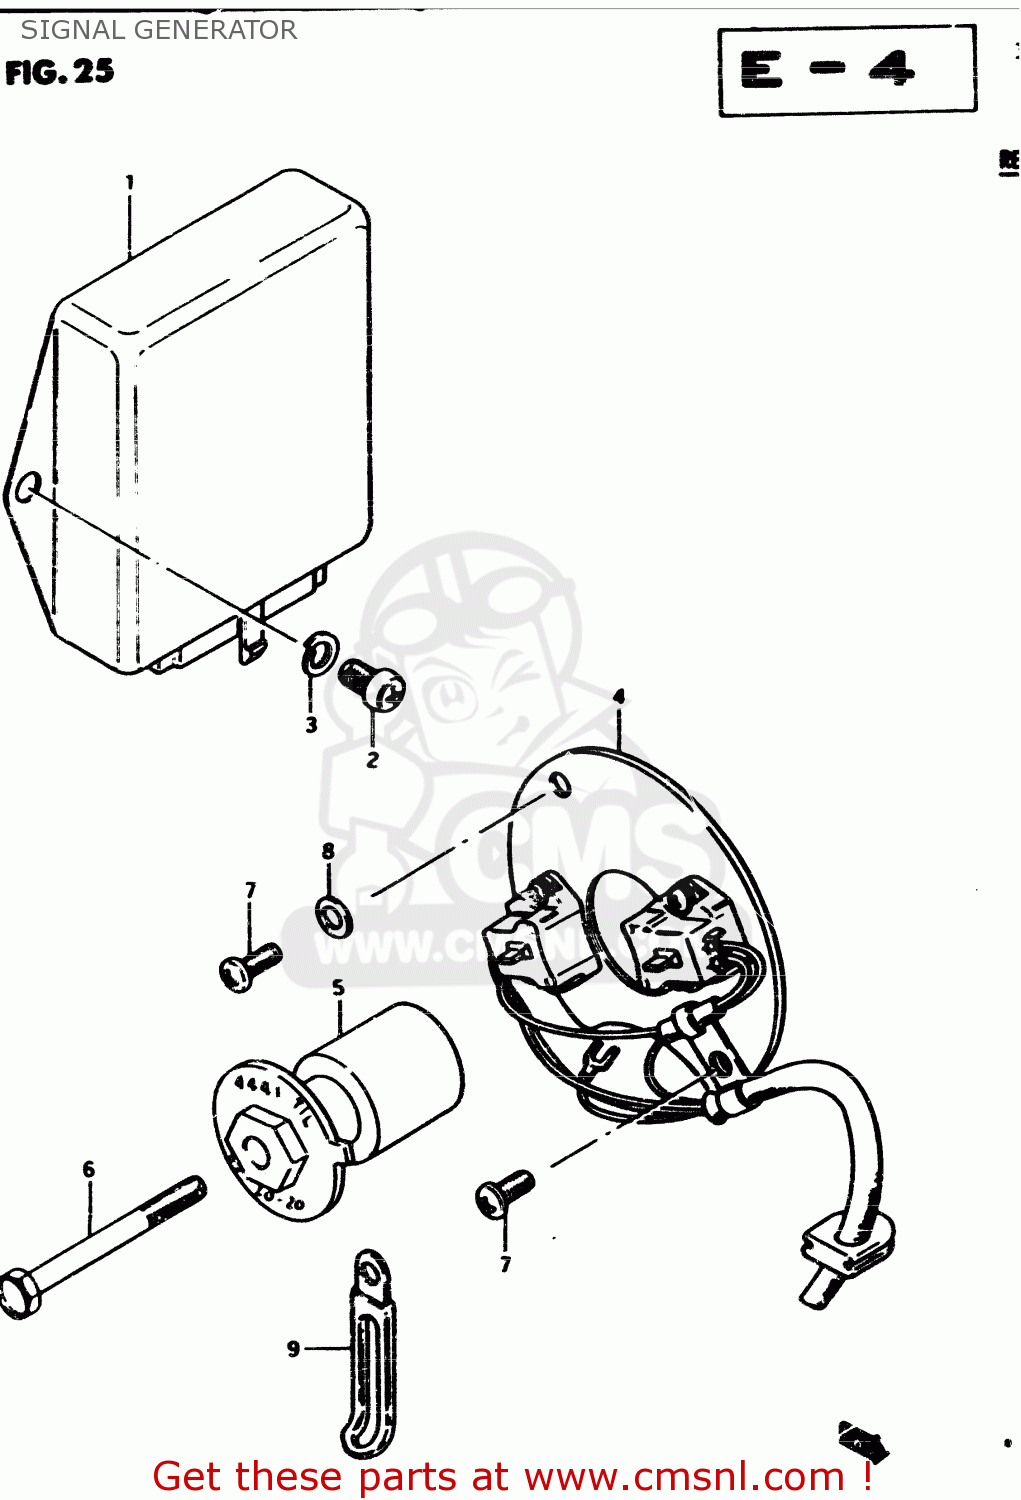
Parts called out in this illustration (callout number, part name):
1	IGNITOR UNIT
2	SCREW
3	LOCK WASHER
4	SIGNAL GENERATOR ASSY
5	ROTOR,SIGNAL
6	BOLT 6X60
7	SCREW(5X12)
8	WASHER
9	CLAMP L:35
